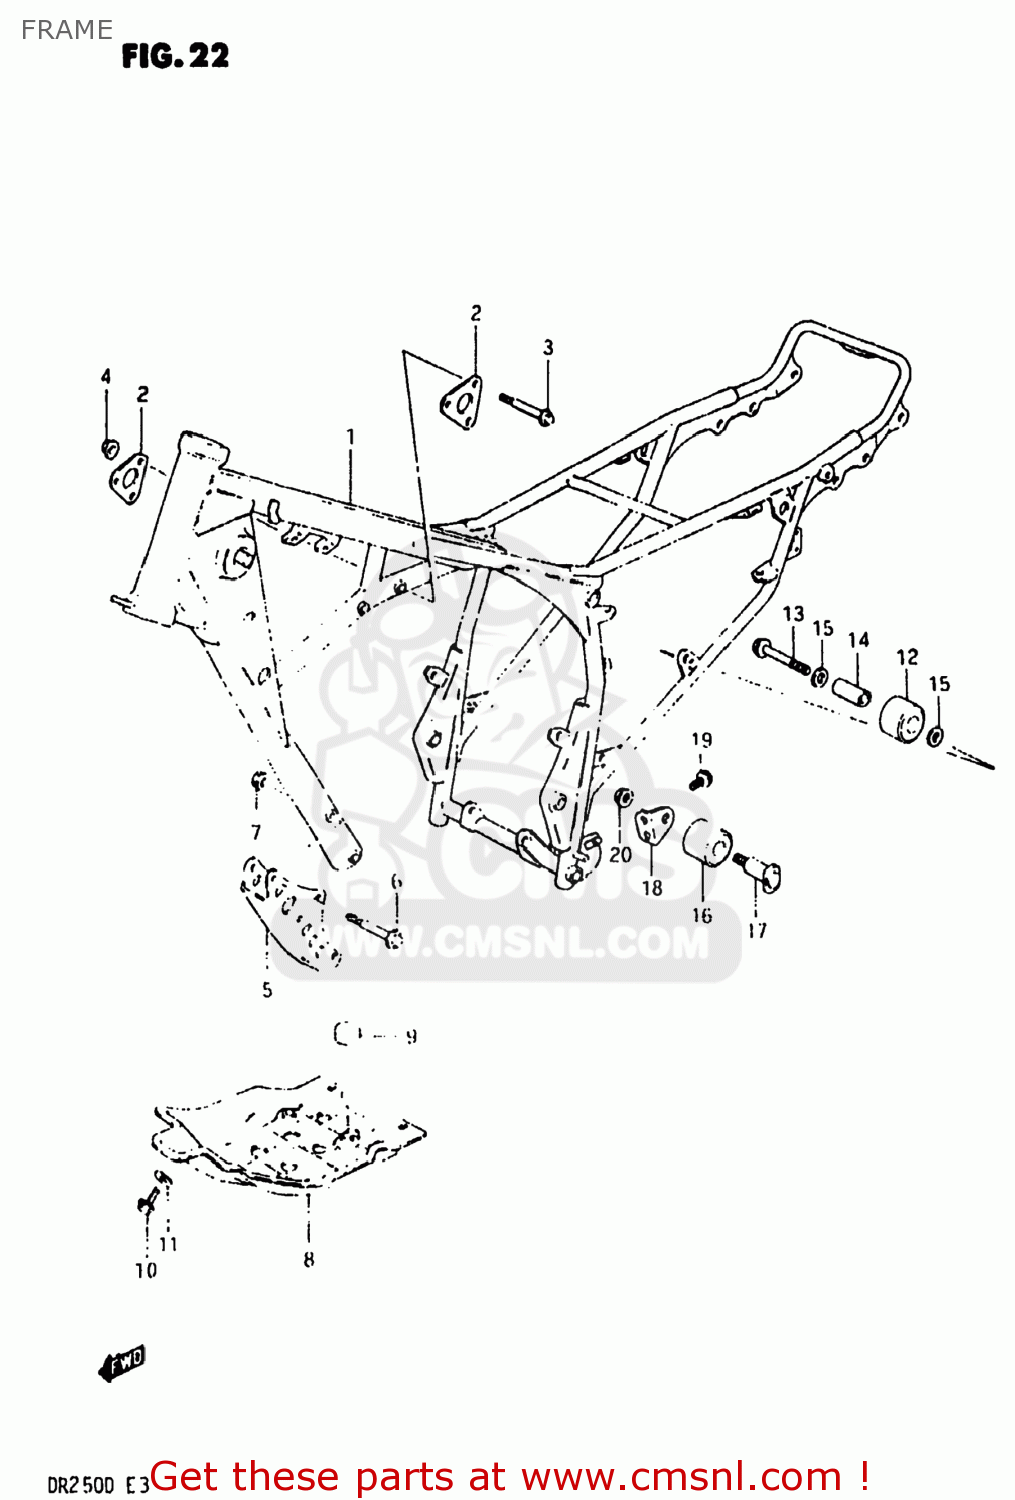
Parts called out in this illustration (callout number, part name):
1	FRAME
2	PLATE,ENGINE MOUNT UPR
3	BOLT
4	NUT
5	PLATE,ENGINE MOUNTING
6	BOLT
7	NUT
8	PROTECTOR,ENGINE
9	CUSHION
10	BOLT
11	WASHER
12	ROLLER,CHAIN LENGTH CONTROL
13	BOLT(8X45)
14	SPACER,CHAIN LENGTH ROLLER
15	WASHER
16	ROLLER,CHAIN LENGTH CONTROL
17	ROLLER,CHAIN
18	BRACKET,LOWER
19	BOLT
20	NUT
